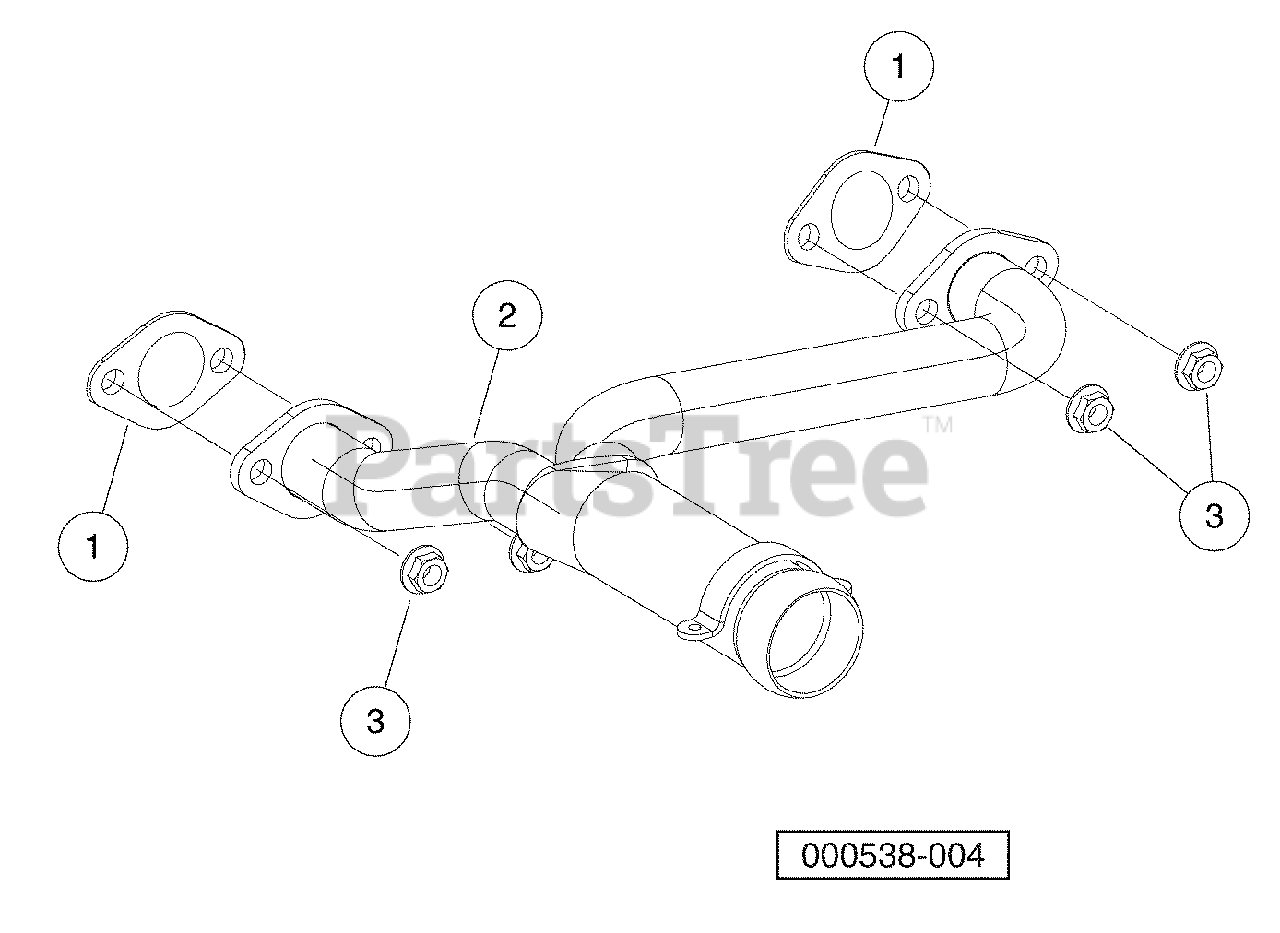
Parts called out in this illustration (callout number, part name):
1	Gasket, Exhaust Header, Fh680d
2	Header, Exhaust, Gas, Fh680d
3	Nut Flg, M8 X 1.25 Serrated
